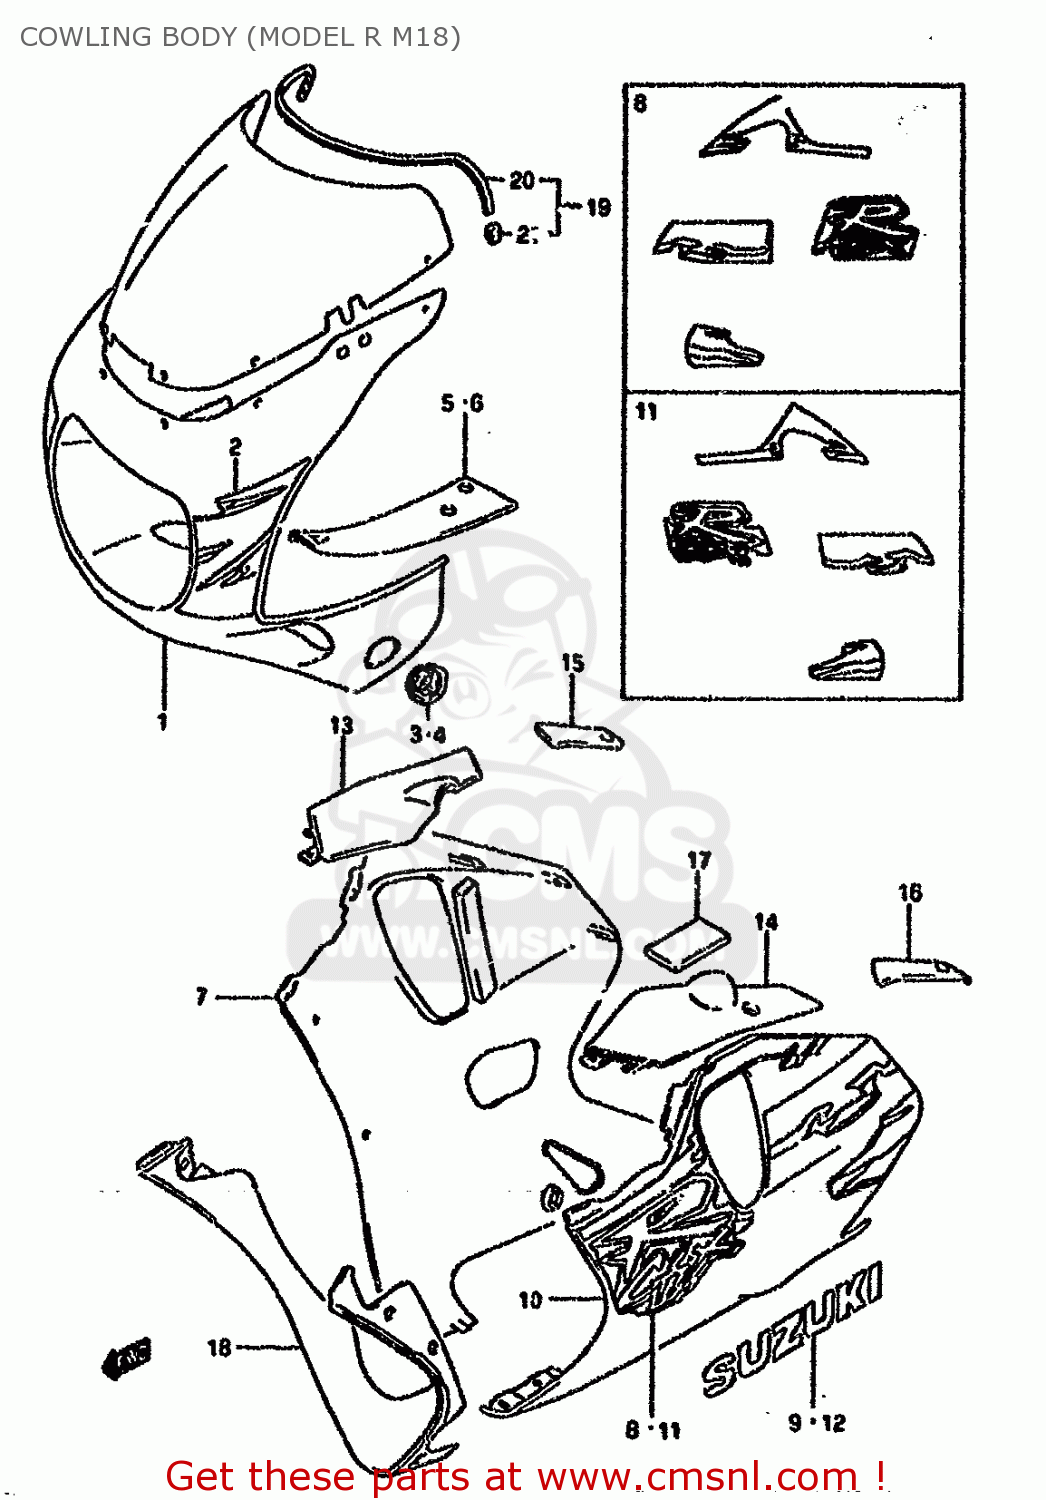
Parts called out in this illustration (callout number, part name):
1	COWLING ASSY,BODY
2	TAPE SET,COWLING BODY
3	PLATE,TURN SIGNAL,RIGHT
4	PLATE,TURN SIGNAL,LEFT
5	PANEL,COWLING,UPPER,RIGHT
6	PANEL,UPPER,LEFT
7	COWLING ASSY,UNDER,R
8	TAPE SET,COWL UNDER,R
9	EMBLEM,CWL.UND
10	COWLING ASSY,UNDER,L
11	TAPE SET,COWL UNDER,L
12	EMBLEM,CWL.UND
13	PANEL,LWR FR,R
14	PANEL,LWR FR,L
15	PANEL,LWR RR,R
16	PANEL,LWR RR,L
17	CUSHION,PANEL
18	COWLING,UNDER CTR
19	WINDSCREEN SET
20	MOLDING WINDSCREEN
21	CLIP,WINDSCREEN MOLDING
